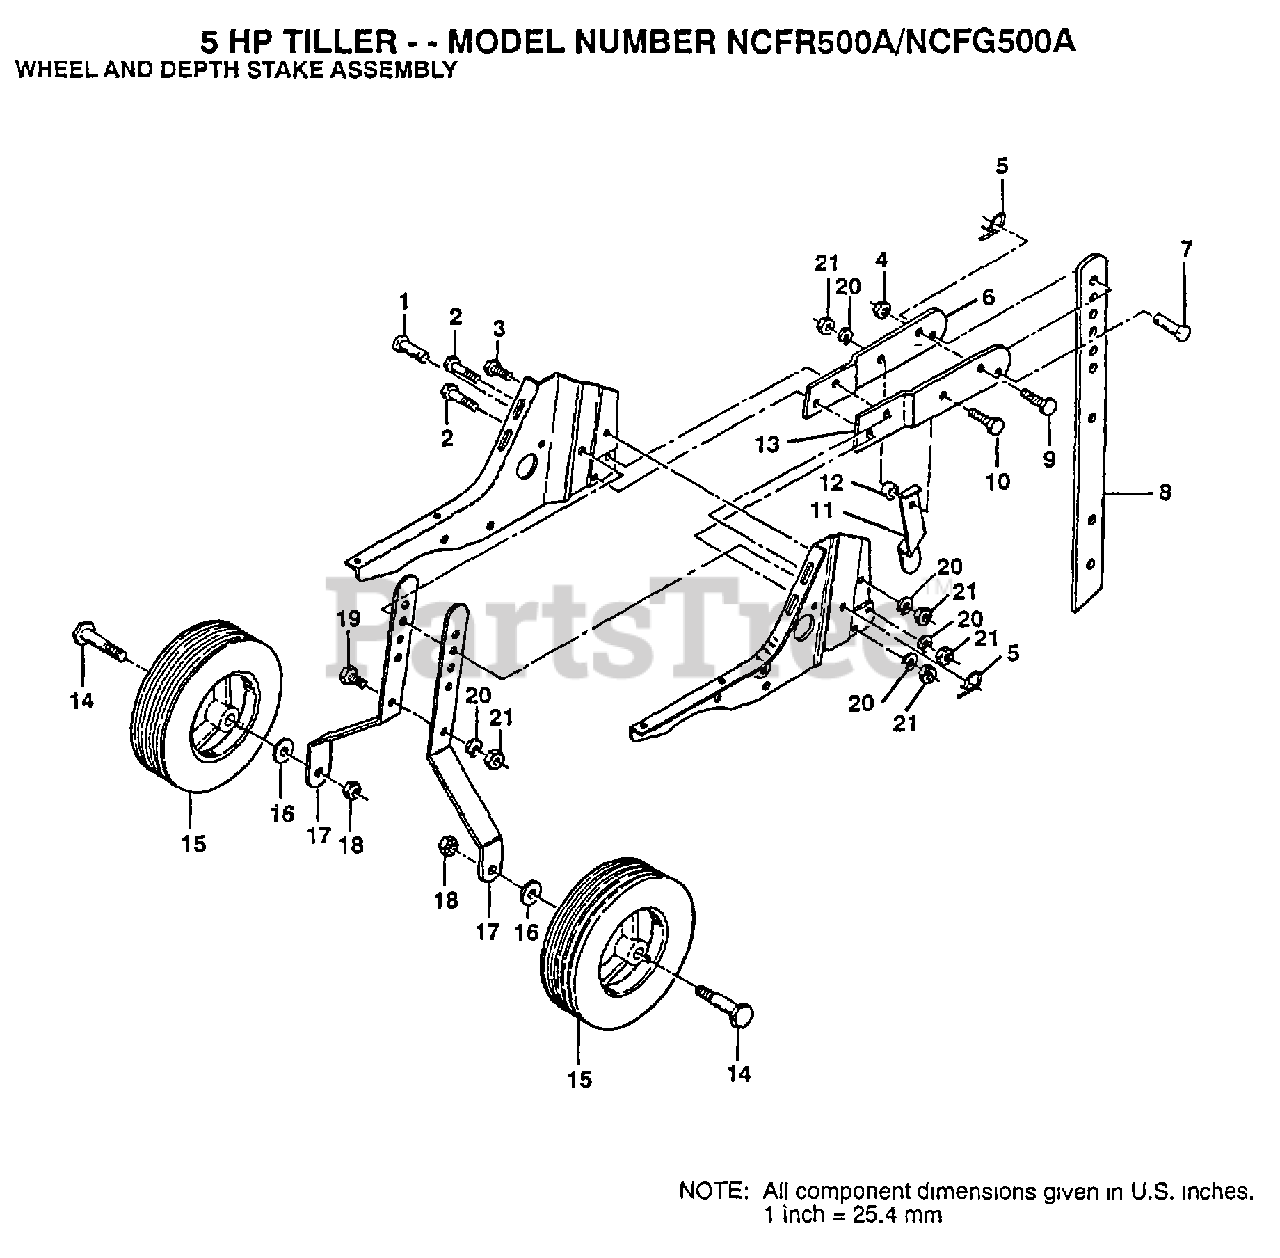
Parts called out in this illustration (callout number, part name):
1	DRILLED RIVET RT
3	BOLT
4	GRIPCO NUT
5	SPRING.RETAINER
9	BOLT.3/8-24X1-1/2
10	BOLT.HEX.5/16-1.5
11	STAKE SPRING TI
12	WASHER
14	BOLT SHOULDER
16	WASHER
19	BOLT
20	LOCKWASHER
21	NUT.HEX.5/16-18
